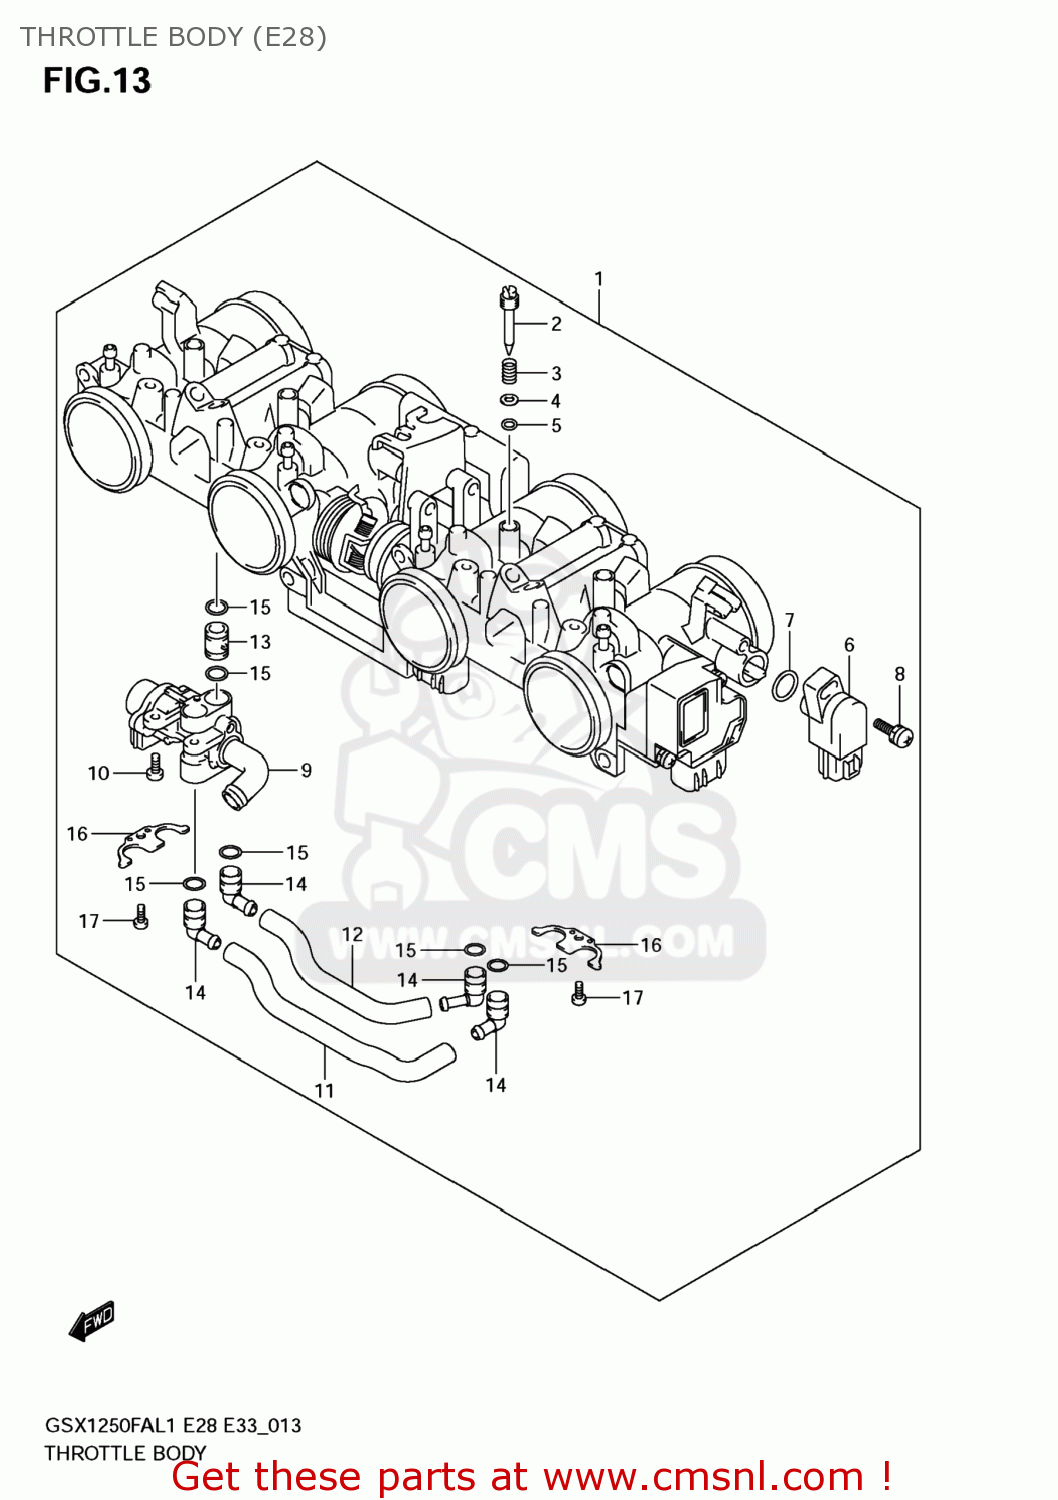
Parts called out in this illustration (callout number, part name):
1	BODY ASSY,THROTTLE
2	SCREW
3	SPRING,THROTTLE SCREW
4	WASHER
5	O RING,PILOT AIR SCREW
6	SENSOR
7	O RING
8	SCREW
9	ACTUATOR
10	SCREW
11	HOSE
12	HOSE
13	PIPE
14	NIPPLE
15	O RING
16	PLATE
17	SCREW
